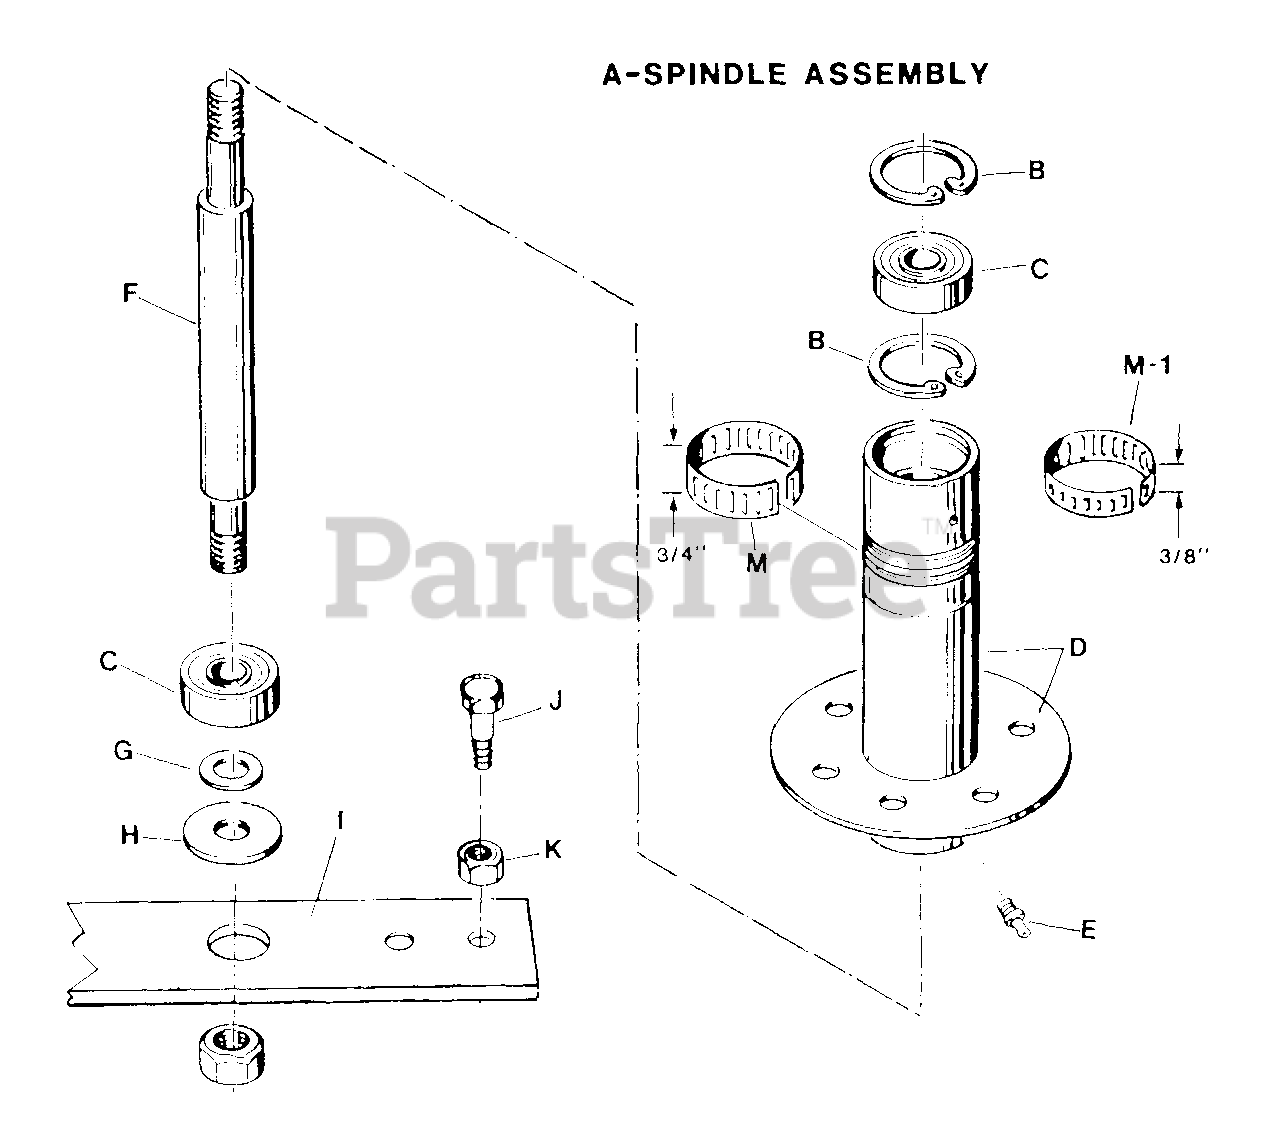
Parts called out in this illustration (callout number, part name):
A	SPINDLE ASSEMBLY
B	RING, RETAINING
C	BEARING, BALL
D	HOUSING, SPINDLE
E	FITTING, Lube (Press fit for .187 hole-no ball)
F	SPINDLE, Shaft (10.237" Long)
G	WASHER, SHIM
I	HOLDER
J	SCREW, 1/2-20 x 1 HEX HEAD CAP
K	NUT, 1/2-20 HEX JAM
L	NUT, 5/8-18 HEX LOCK
M	TOLERENCE- RING, 3/4" WIDE
M1	TOLERENCE- RING, 3/8" WIDE
